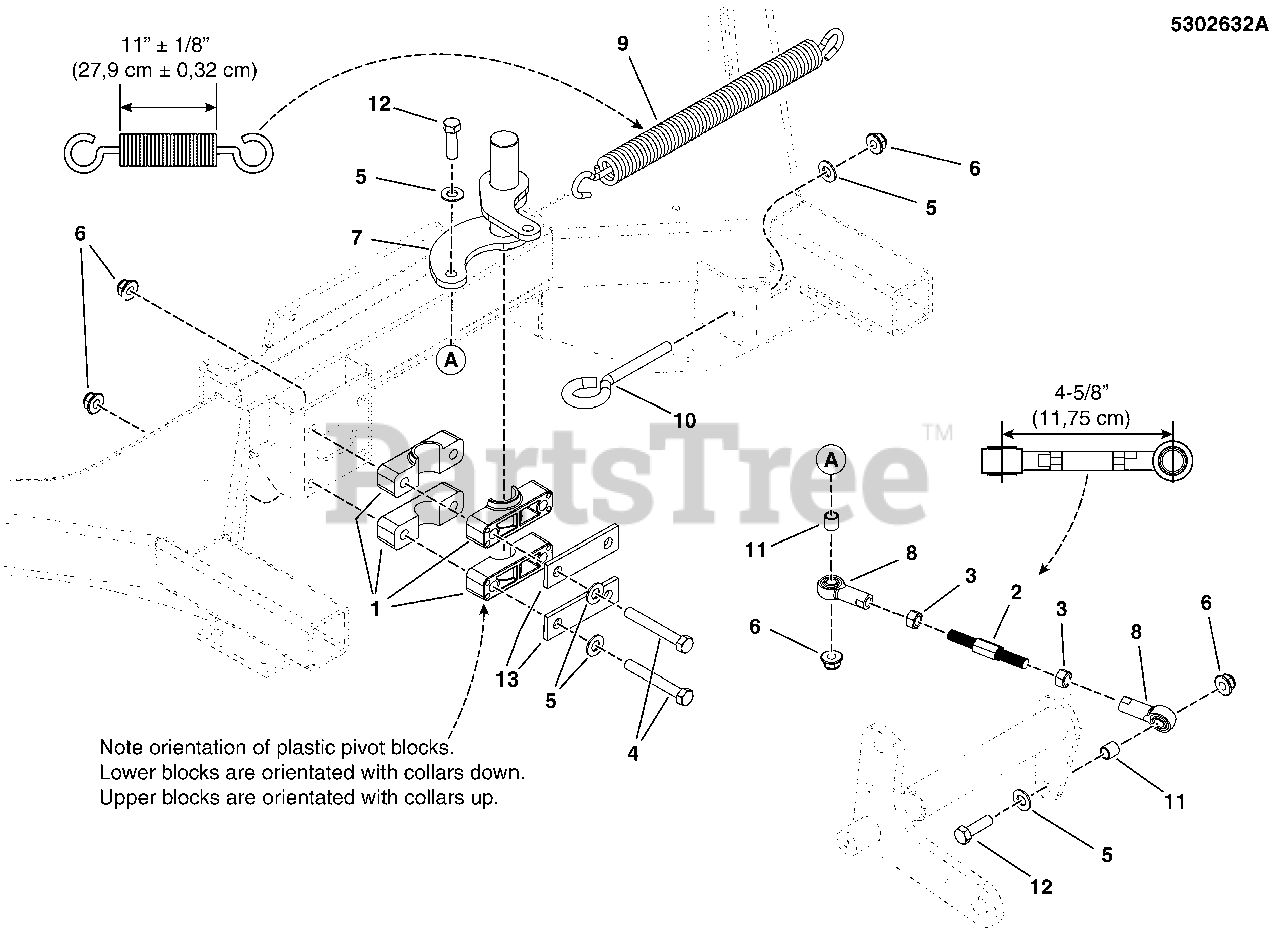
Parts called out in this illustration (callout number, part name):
1	PIVOT BLOCK, PLASTIC
2	LINK, ADJUSTABLE, SHORT
3	NUT, 3/8-24 HEX
4	BOLT, 3/8-16 X 2-3/4" GD5 CZ
5	WASHER, 3/8 SAE
6	NUT, 3/8-16 HEX NYLOCK FLANGE
7	WELD, PIVOT, LIFT ASSIST - RED
8	BALL JOINT, 3/8-24 FEMALE
9	SPRING-EXT, 1.00 ODX13.25LGX.177WR, BLK
10	EYE BOLT, 3/8-16 X 5, 2.88THRD, 1EYE, CZ
11	SPACER, .38 X .50 X .50
12	BOLT, 3/8-16 X 1-1/2" GD5 CZ
13	PLATE, PIVOT BLOCK SUPPORT - BLK
